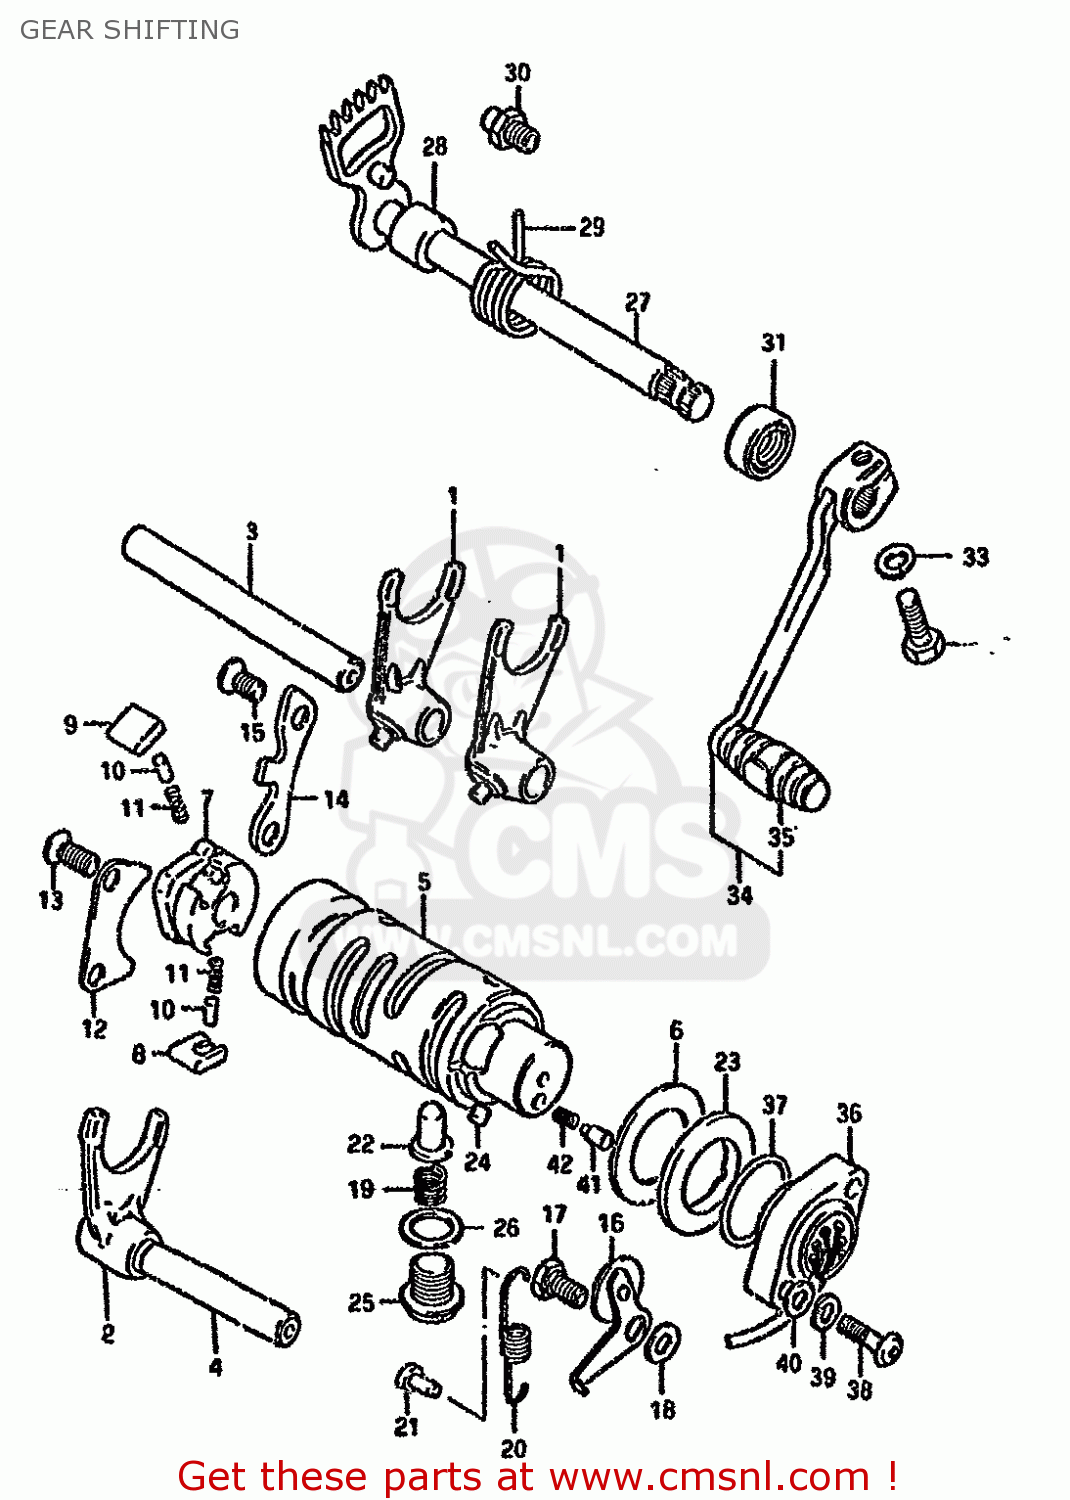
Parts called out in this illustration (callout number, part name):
1	FORK,GEAR SHIFT NO.2
2	FORK,GEAR SHIFT NO.3
3	SHAFT,GEAR SHIFT FORK
4	SHAFT,GEAR SHIFT FORK
5	CAM,GEAR SHIFT
6	WASHER,THRUST
7	GEAR,GEARSHIFT CAM DRIVE
8	PAWL,GEAR SHIFT NO.1
9	PAWL,GEAR SHIFT NO.2
10	PIN(5X8)
11	SPRING
12	LIFTER,GEAR SHIFT POLE
13	SCREW
14	GUIDE,GEAR SHIFT CAM
15	SCREW
16	STOPPER,GEAR SHIFTING
17	BOLT(6X14.6)
18	WASHER
19	SPRING
20	SPRING
21	RIVET
22	STOPPER,GEAR SHIFT CAM NO.2
23	PLATE,GEAR SHIFT CAM STOPPER
24	PIN 4X6
25	PLUG(14X12)
26	GASKET(14X19.2X2) (NAS)
27	SHAFT,GEAR SHIFT
28	SPACER(12X20X15.3)
29	SPRING
30	STOPPER,GEAR SHIFT CAM
31	OIL SEAL
32	BOLT
33	WASHER,LOCK
34	LEVER ASSY,GEAR SHIFT
35	RUBBER,GEAR SHIFT PEDAL
36	TERMINAL BASE,NEUTRAL SWITCH
37	O-RING (D:2.4 ID:26.2)
38	SCREW
39	LOCK WASHER
40	WASHER
41	PIN(5X15.5)
42	SPRING
